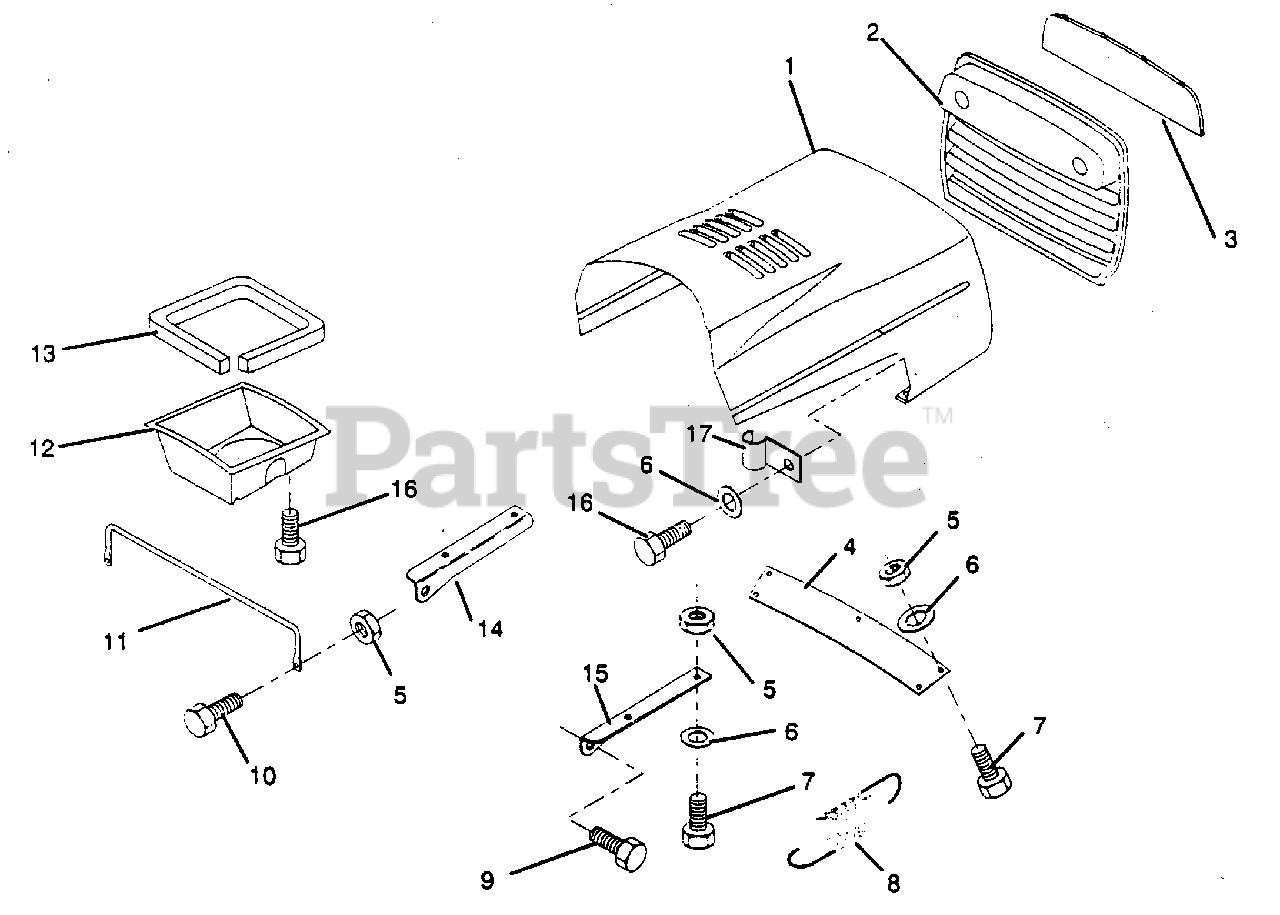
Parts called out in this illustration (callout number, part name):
1	Hood (AYP part number)
2	Grill (AYP part number)
3	Lens (AYP part number)
4	Strap, Grill (AYP part number)
5	Nut, Hex Keps 1/4-20 UNC (AYP part number)
6	Washer 9/32 x 5/8 x 16 Ga. (AYP part number)
7	Bolt, Hex Fin. 1/4 - 20 UNC x 5/8 Gr. 5 (AYP part number)
8	Spring, Extension (AYP part number)
9	Bolt, Thrd. Forming Shoulder (AYP part number)
10	Bolt, Hex Fin. 14-20 x 3/4 Gr. 5 (AYP part number)
11	Brace, Hood (AYP part number)
12	Duct, Air (AYP part number)
13	Strip, Foam (AYP part number)
14	Bracket, Hood, L.H. (AYP part number)
15	Bracket, Hood, R.H. (AYP part number)
16	Screw, Fin. Hex #13-16 Hi-Lo x 5/8 (AYP part number)
17	Clip, Fuel Line (AYP part number)
